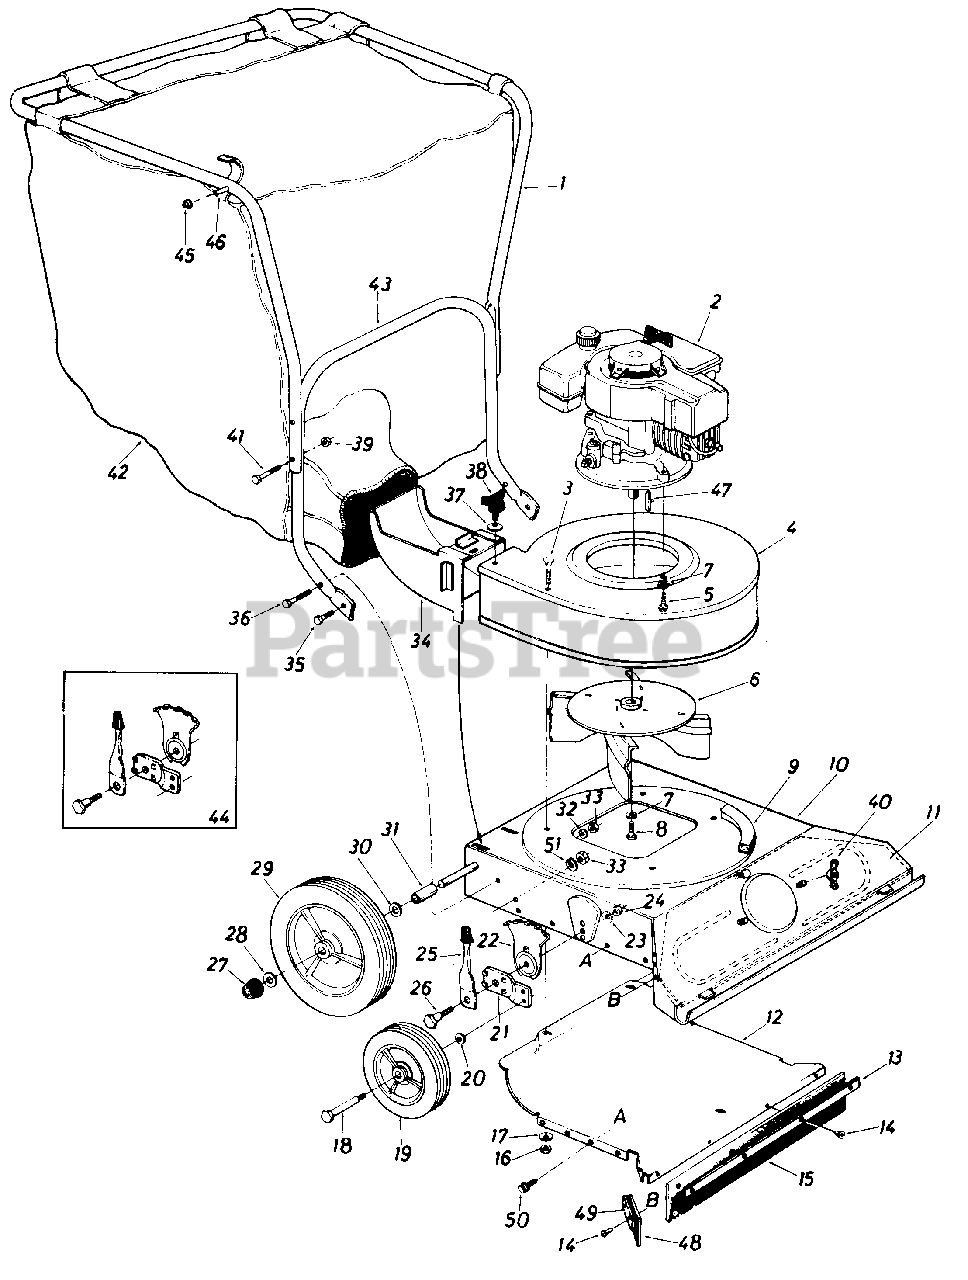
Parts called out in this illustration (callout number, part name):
1	Upper Handle
2	Engine
3	Carriage Bolt 5/16-18 x .62" Lg.
4	81Ower Housing Ass'y.
5	Hex Tap Scr. 3/8-16 x 1.00" Lg.
6	Impeller Ass'y.
7	L.-Wash 3/8" I.D.
8	Hex Bol. 3/8-24 x 1.0" Lg. w/Patch
9	P.V.C. Foam Strip (4-Pcs. 12" Lg.)
10	Vacuum Deck Ass'y.
11	Front Baffle Ass'y.
12	Lower Baffle Ass'y
13	Wiper Retaining Strip
14	Pop Rivet .188" Dia.
15	Nozzle Wiper Rear
16	Hex Nut 5/16-18 Thd.
17	Bell.-Wash. .34" I.D. x .87" O.D.
18	Shld. Bolt 1/2" Dia. x 1.45" Lg. (3/8-18)
19	Wheel Ass'y. Comp. 8 x 1.75" - Front
20	Bell. Wash. .39" I.D. x 1.12" O.D.
22	Index Plate
23	Bell.-Wash. .39" I.D. x N 1.12" O.D.
24	Hex Nut 3/8-16 Thd.
25	Spring Lever Ass'y. w/Knob
26	Shoulder Bolt .500" x 7/16" 4. (3/8-16)
27	Push Cap 50" Rod (Black)
28	Fl.-Wash. 1/2" I.D. x 1.0" O.D. x .06
29	Wheel Ass'y. Comp. 10 x 1.75" - Rear
30	Fl.-Wash. 1/2" I.D. x 1.0" O.D. x .06
31	Wheel Spacer 1/2" I.D. x 15/16" Lg.
32	Bell.-Wash. .39" I.D. x 1.12" O.D.
33	Hex Nut 3/8-16 Thd.
34	Air Duct Ass'y.
35	Hex Bolt 3/8-16 x .75" Lg.
36	Hex Bolt 3/8-16 x 1.50" Lg.
37	Bell.-Wash. .34" I.D. x .87" O.D.
38	Thumb Scr. 5/16-18 x .75" Lg.
39	Hex Cent. L.-Nut 1/4-20 Thd.
40	Wing Nut 1/4-20 (Plastic)
41	Hex Bolt 1/4-20 x 1.75" Lg.
42	Vacuum Bag (6.6 Bushel)
43	Lower Handle
44	Height Adjuster Ass'y. Comp.-R.H.
45	Push Speed Nut .25" Dia.
46	Stud Pin .250" Dia. x 1.75" Lg.
47	Sq. Key 3/16 x 3/16 x 1.00" Lg.
48	Nozzle Wiper Side
49	Wiper Retaining Strip
50	Hex Wash. Hd. "F" Tap Scr. #10
51	L-Wash. 3/8" I.D.
